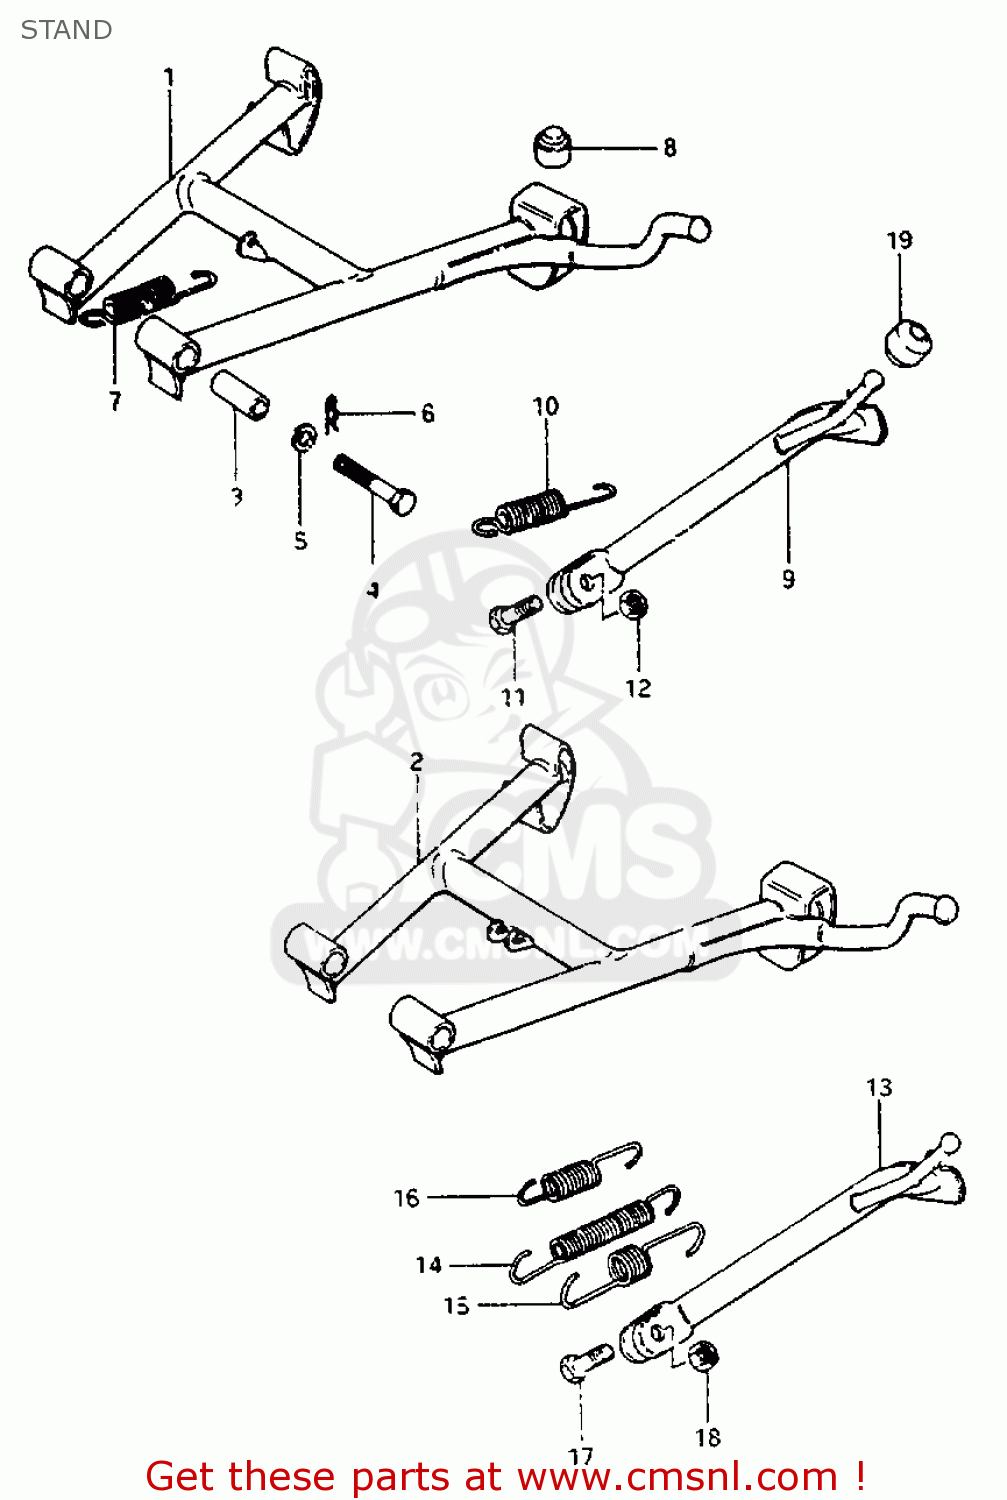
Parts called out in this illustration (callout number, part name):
1	STAND,CENTER
3	SPACER(10X16X38.8)
4	BOLT
5	LOCK WASHER
6	CLIP
7	SPRING
8	CUSHION
9	STAND, PROP
10	SPRING
11	BOLT(10X30)
12	NUT
19	CUSHION
